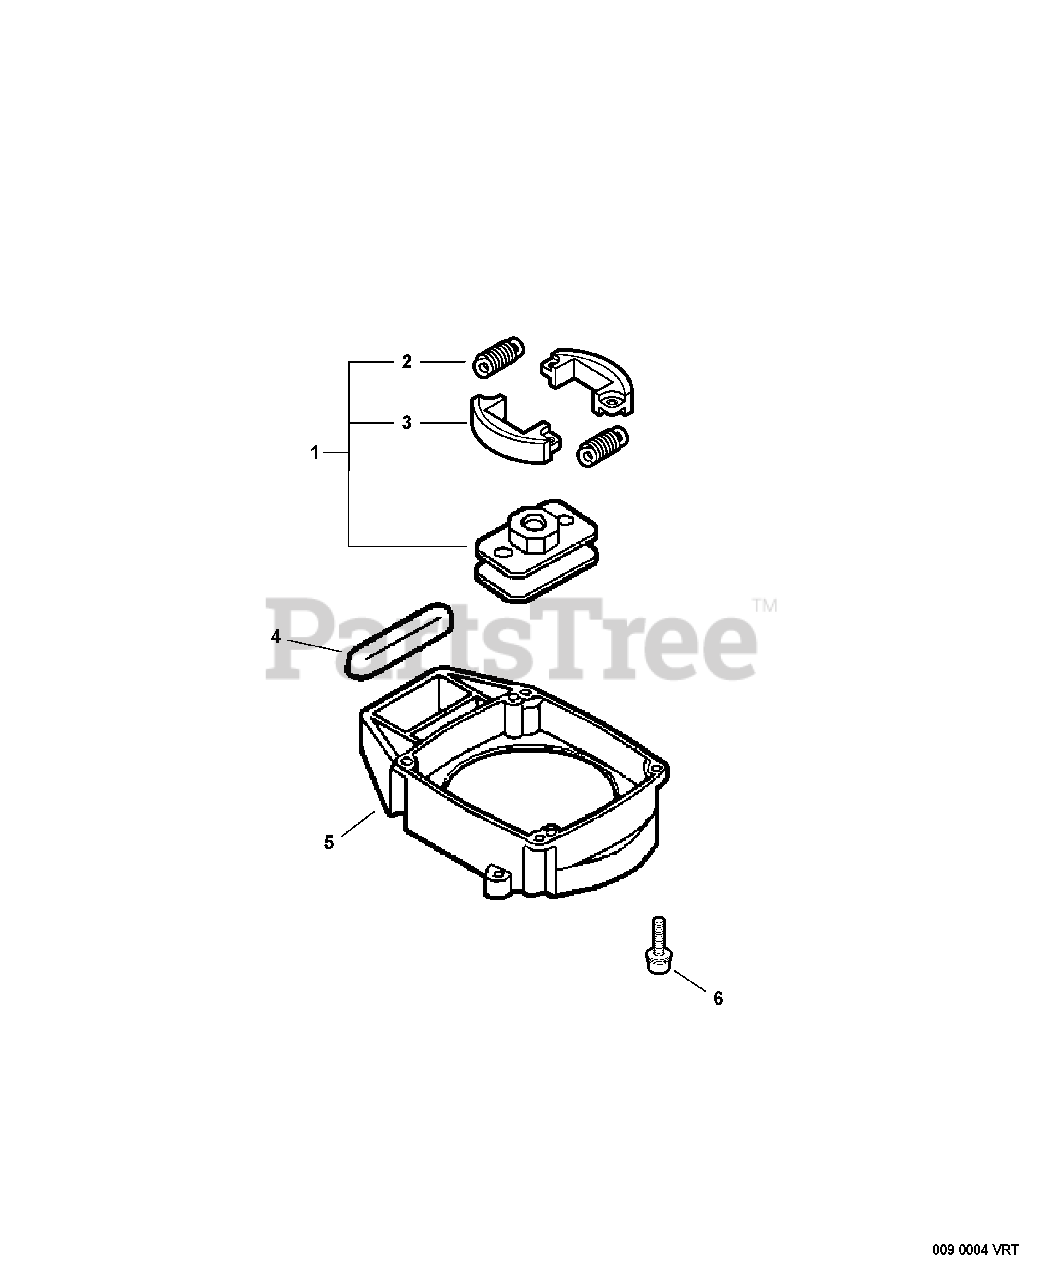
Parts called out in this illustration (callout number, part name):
1	CLUTCH ASSY
2	SPRING, CLUTCH
3	SHOE, CLUTCH
4	CUSHION, FUEL TANK
5	CASE, CLUTCH
6	SCREW - 4X14
